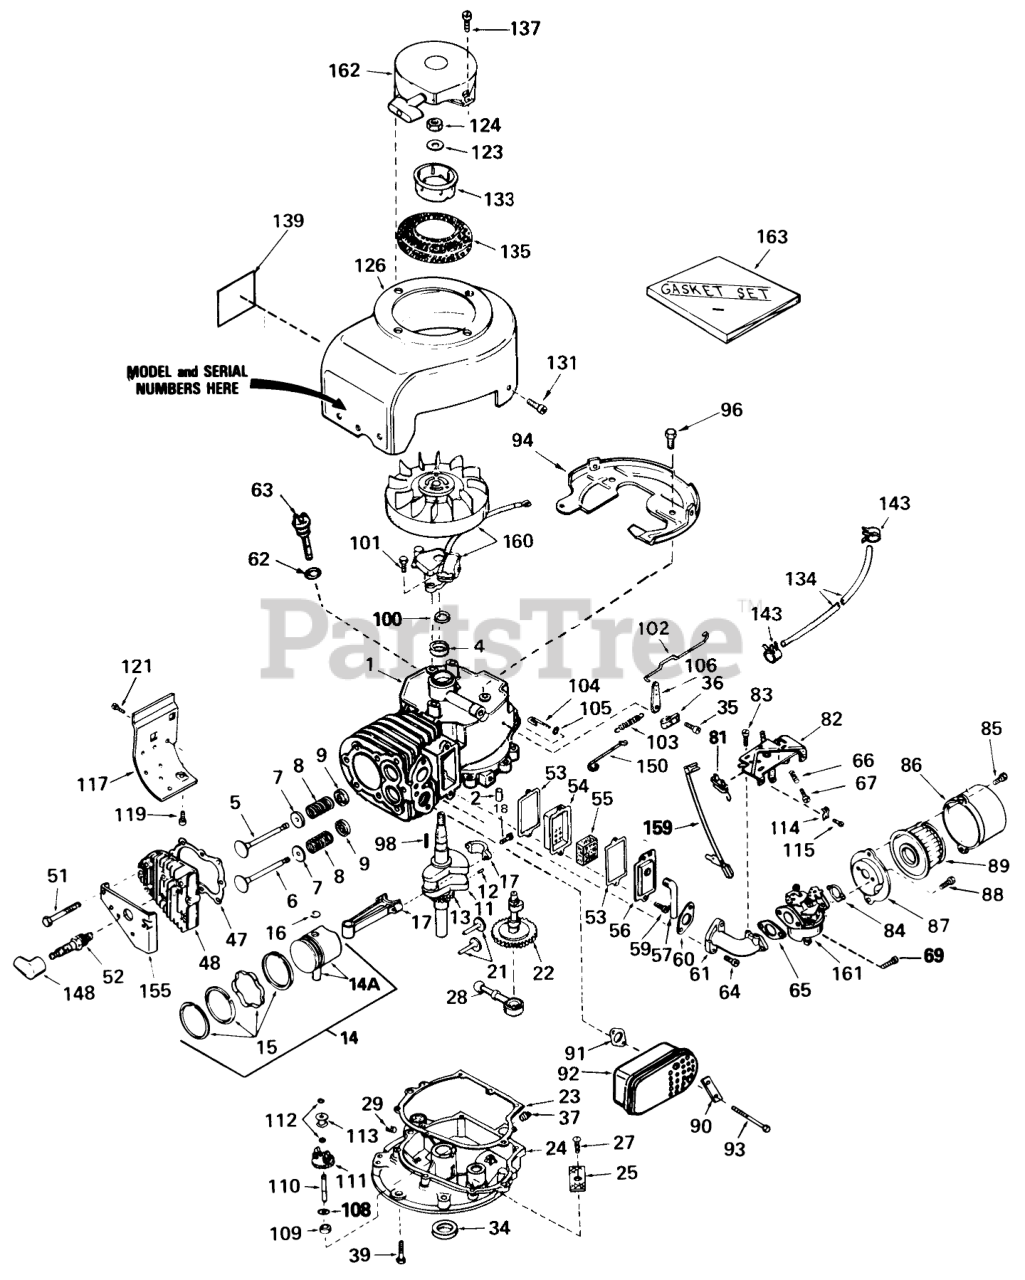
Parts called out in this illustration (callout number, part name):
1	Cylinder Assy. (Incl. Ref. #2, 4 & 63)
2	Pin-Dowel
4	Oil Seal
5	Valve, Intake (Std.)(Incl. Ref. #9)
5	Valve, Intake (1/32" Oversize)(Incl. Ref. #9)
6	Valve, Exhaust (Std.)(Incl. Ref. #9)
6	Valve, Exhaust (1/32" Oversize)(Incl. Ref. #9)
7	Cap-Spring, Valve
8	Spring-Valve
9	Keeper-Spring, Valve
11	Crankshaft Assy. (Incl. Ref. #12 & 13)
12	Pin, Groove
13	Gear-Crankshaft
14	Piston, Pin & Ring Assy. (Std.)(Incl. Ref. #14A, 15 & 16)
14	Piston, Pin & Ring Assy. (.010 Oversize)(Incl. Ref. #14A, 15 & 16)
14	Piston, Pin & Ring Assy. (.020 Oversize)(Incl. Ref. #14A, 15 & 16)
14A	Piston & Pin Assy. (Std.)(Incl. Ref. #16)
14A	Piston & Pin Assy. (.010 Oversize)(Incl. Ref. #16)
14A	Piston & Pin Assy. (.020 Oversize)(Incl. Ref. #16)
15	Ring Set, Piston (Std.)
15	Ring Set, Piston (.010 Oversize)
15	Ring Set, Piston (.020 oversize)
16	Ring-Retaining, Piston Pin
17	Rod Assy., Connecting (Incl. Ref. #18)
18	Bolt, Connecting Rod
21	Lifter-Valve
23	Gasket-Cover, Cylinder
24	Flange Assy., Mounting (Incl. Ref. #25, 27, 34, 37, 63 & 110)
25	Screen-Oil Filter
28	Pump, Oil
29	Plug-Pipe (Internal Hex, 1/4-18)
34	Seal-Oil
35	Screw
36	Clamp-Lever, Governor
37	Plug-Drain, Oil (SQH 1/4-18)
39	Screw (1/4-20 x 1-1/4)
47	Gasket-Head, Cylinder
48	Head, Cylinder (Incl. 3 of Ref. #51)
51	Screw (5/16-18 X 2-1/2)
52	Plug, Spark (J17LM or equiv.)
52	Plug, Spark (Champion RCJ-8)
53	Gasket-Breather
54	Body-Breather
55	Element-Breather
56	Cover-Valve
57	Tube-Breather
60	Gasket-Intake
61	Pipe-Intake
62	Gasket
63	Dipstick, Oil (Incl. Ref. #62)
64	Screw (T-30, 5/16-18x1-3/32)
65	Gasket
66	Spring-Compression
67	Screw
69	Screw-Hex Hd.
81	Terminal
82	Control Assy., Speed (Incl. Ref. #66, 67 & 81)
83	Screw (10-24 x 9/16)
84	Gasket
86	Body-Air Cleaner
87	Bracket
88	Screw (10-32 x 1/2)
89	Element
90	Plate-Locking
91	Gasket Exhaust
92	Muffler
93	Screw Hex Hd.
94	Baffle Blower Housing
96	Screw (1/4-20x19/32)
98	Key-Flywheel
100	Gasket Stator
102	Link Governor
103	Spring Governor
104	Rod, Governor (Incl. Ref. #105)
105	Washer-Flat
106	Lever-Governor
108	Washer-Flat
109	Spacer Assy., Governor (Incl. Ref. #108)
110	Shaft, Governor
111	Gear Assy., Governor (Incl. Ref. #108)
112	Ring-Retaining
113	Spool-Governor
114	Conduit
115	Screw (10-32 x 3/8)
117	Emnsion, Blower Housing
121	Screw
123	Washer-Belleville
126	Housing, Blower
131	Screw, Hex Hd.
133	Cup-Starter
134	Line-Fuel
135	Screen, Air
139	Decal-Instruction
143	Clamp-Line, Fuel
148	Cover-Spark Plug
150	Link Governor Spring
155	Cover-Head, Cylinder
159	Wire, Ground
160	Magneto (The complete magneto is not available as an assembly. The magneto number is shown for reference purposes only. Order component parts individually, as shown in parts list.)
161	Carburetor (Incl. Ref. #65)
162	Starter, Rewind
163	Gasket Set
